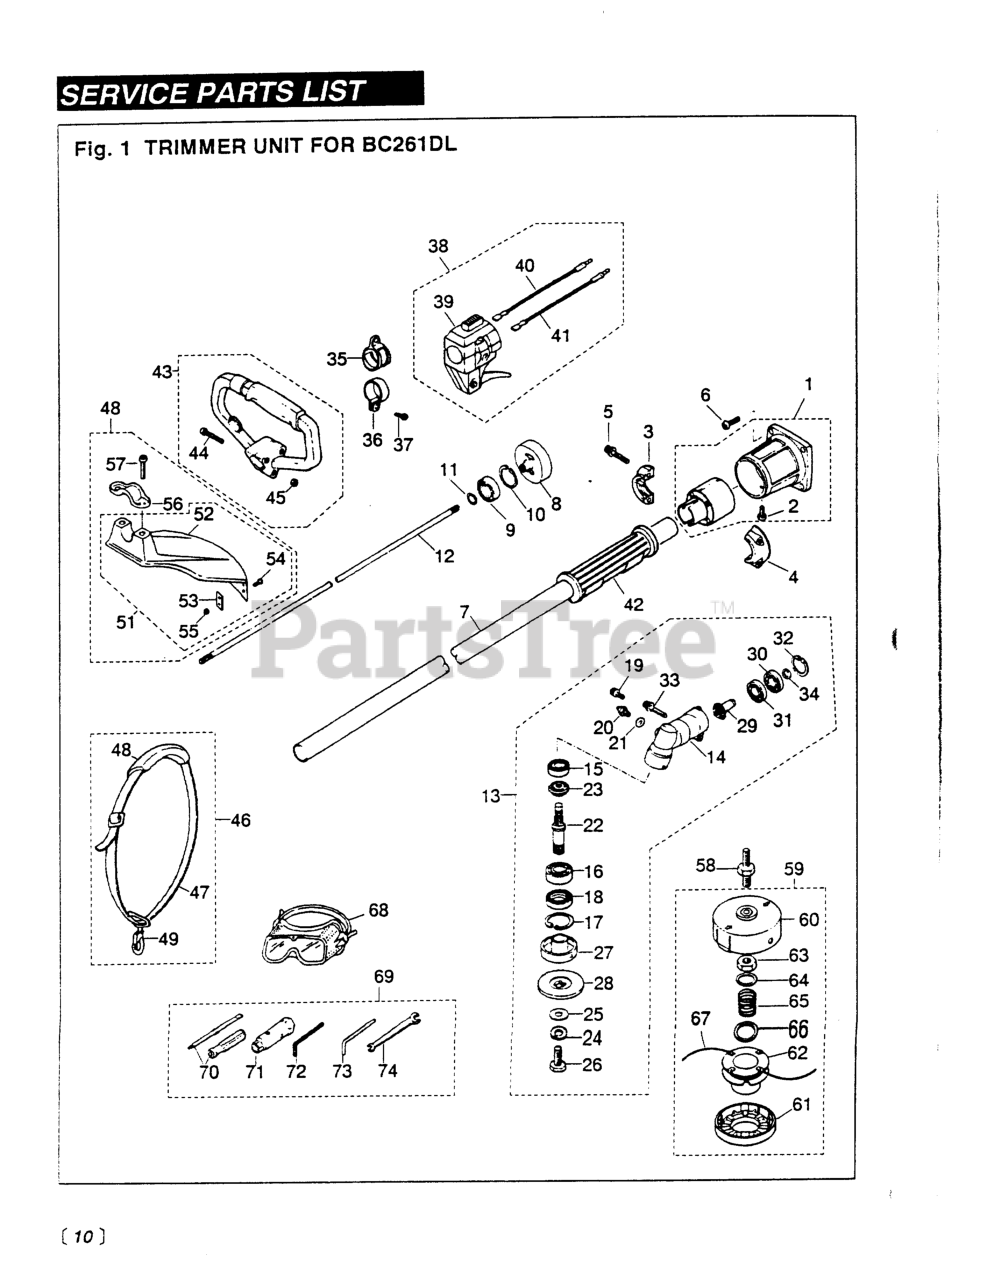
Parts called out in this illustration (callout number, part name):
2	SCREW, M6 x 10
4	CLAMP (L)
5	BOLT
6	BOLT, M6 X 20
8	DRUM CLUTCH (USE 6460-12112)
9	BEARING
10	RING, SNAP, M28 x 1.2
16	BEARING
17	RING, SNAP, M28 x 1.2
18	SEAL, OIL
19	BOLT, M5 X 10
20	FITTING, GREASE
21	WASHER, M6 X .8
22	SHAFT, GEAR (NLA)
23	GEAR, BEVEL (NLA)
24	WASHER (RPLS 3180-13270)
25	WASHER, M8 x 2.3 (RPLS -20823)
26	BOLT, LH
27	HOLDER (NLA)
28	HOLDER (B)
29	PINION (NLA)
30	BEARING (RPLS T3300-13531)
31	BEARING (RPLS T3403-13530)
32	RING, SNAP, M24 x 1.2
33	BOLT
34	RING, SNAP (RPLS T3300-13330)
35	HANGER (USE -18101)
37	SCREW, M5X20 (RPLS.1400-75510)
38	LEVER ASSEMBLY
40	CORD-A, BLACK
41	CORD-B, RED
43	HANDLE ASSEMBLY (NLA)
44	SCREW, M5 x 30(RPLS 0263-00530
45	NUT, M5 X 4
53	BLADE
54	SCREW, M5 x 12
55	NUT
56	CLAMP (REPLACES 5807-24120)
57	BOLT, M6 x 1.30
58	ARBOR, 8MM
59	6
61	COVER
63	NUT (NO LONGER AVAILABLE)
64	PLATE, LARGE
66	PLATE, SMALL
69	TOOL SET
70	SCREWDRIVER
72	WRENCH (TOOL)
73	BAR
74	SPANNER, 8 X 10 (RPLS 2540- )
